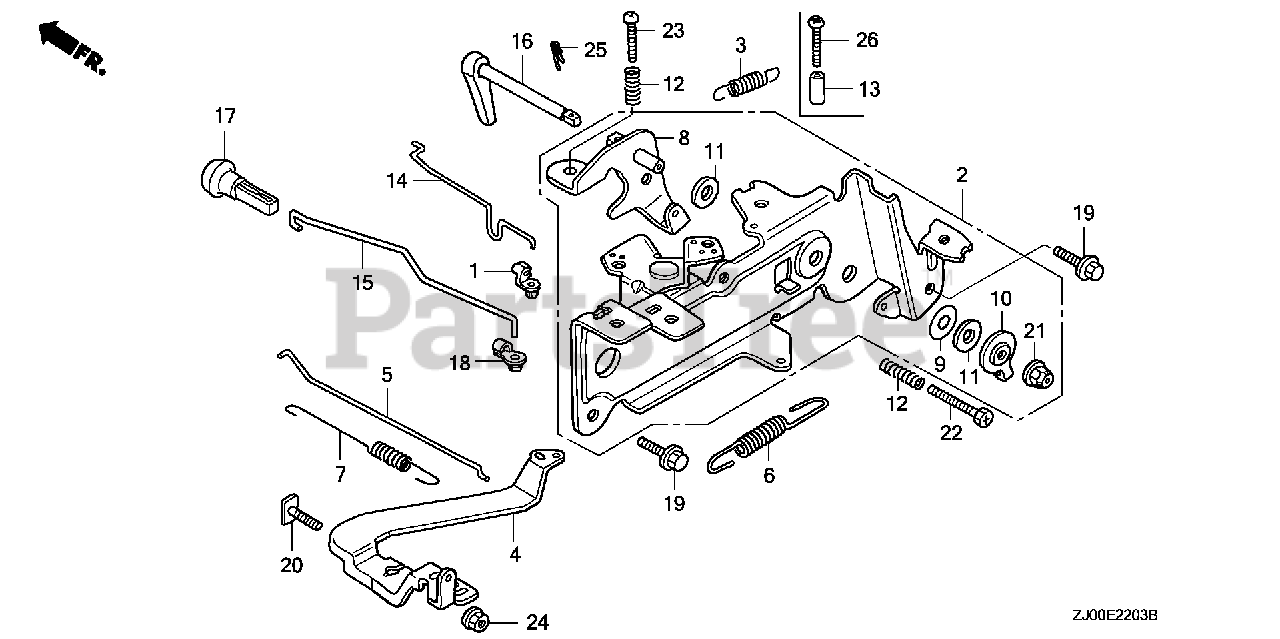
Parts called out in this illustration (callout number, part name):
1	JOINT, ROD
2	CONTROL ASSY.
3	SPRING, STARTER
4	ARM, GOVERNOR
5	ROD, GOVERNOR
6	SPRING, GOVERNOR (MANUAL)
7	SPRING, THROTTLE RETURN
8	ARM, CONTROL
9	SPRING, LEVER
10	WASHER, CONTROL ARM
11	SPACER, CONTROL LEVER
12	SPRING, CONTROL ADJUSTING
14	ROD, CHOKE CONTROL
15	ROD, CHOKE KNOB
16	LEVER ASSY., THROTTLE
17	KNOB, CHOKE
18	BUSH, LINKAGE
19	BOLT, FLANGE (6X14) (CT200)
20	BOLT, GOVERNOR ARM
21	NUT, SELF-LOCK (6MM)
22	BOLT, RECESSED (5X25)
23	SCREW, PAN (5X25)
24	NUT, FLANGE (6MM)
25	PIN, LOCK (10MM)
